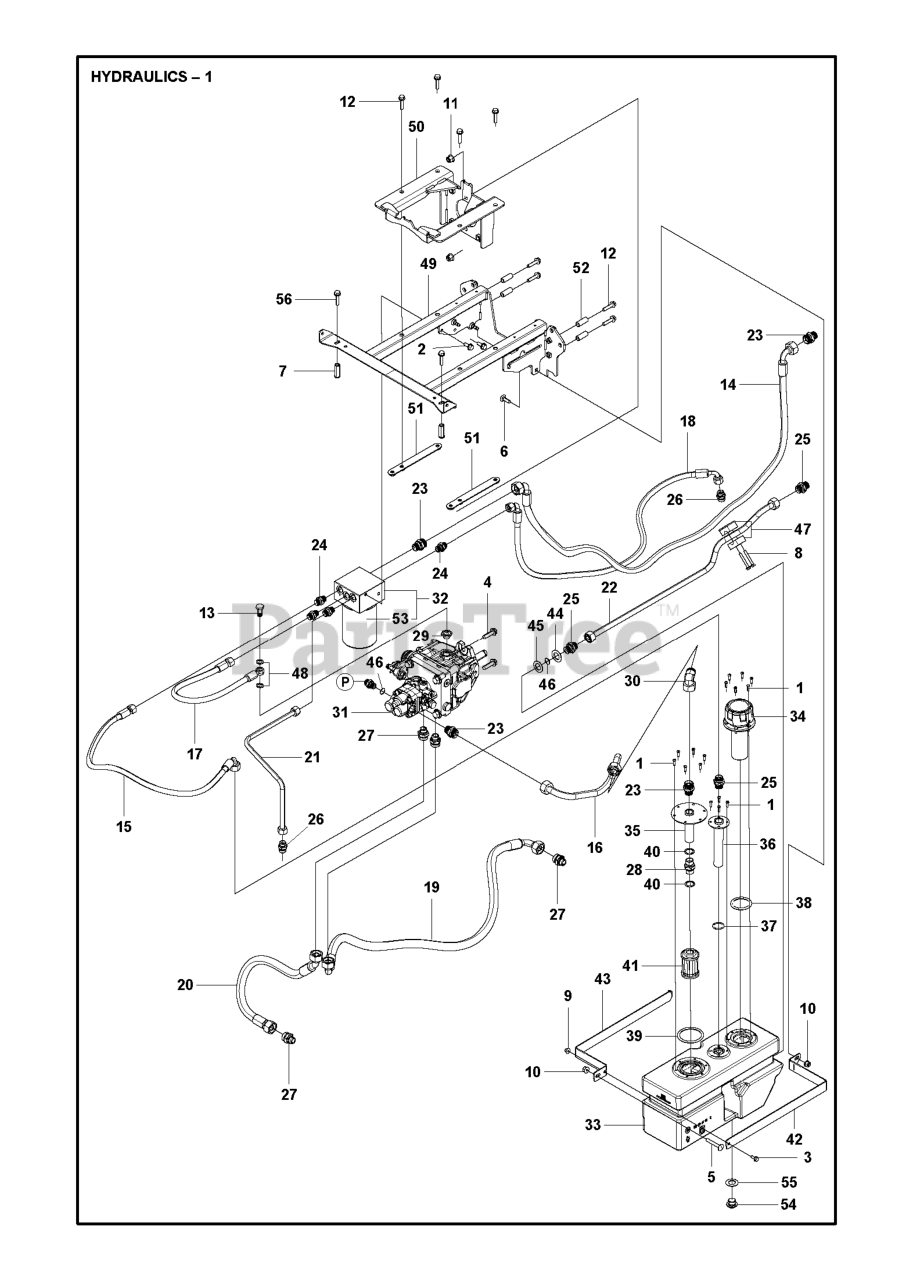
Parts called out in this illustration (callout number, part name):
1	SCREW ITXPANT T50X16 ZN/FE (A
3	BOLT FLANGE - M6X20
9	NUT FLANGE
10	NUT FLANGE
12	SCREW EHHFM
28	PIPE FITTING G STRAIGHT 1/2-1/
37	O-RING 26.2X3.0 NITRILE
38	O-RING 47.2X5.7 NITRIL
39	O-RING 61.2X5.7 NITRIL
41	FILTER PUMP SUCTION, AWD
46	REPL BY 740 48 14-02
48	GASKET 20X14X1.5 COPPER
56	SCREW EHHFM
